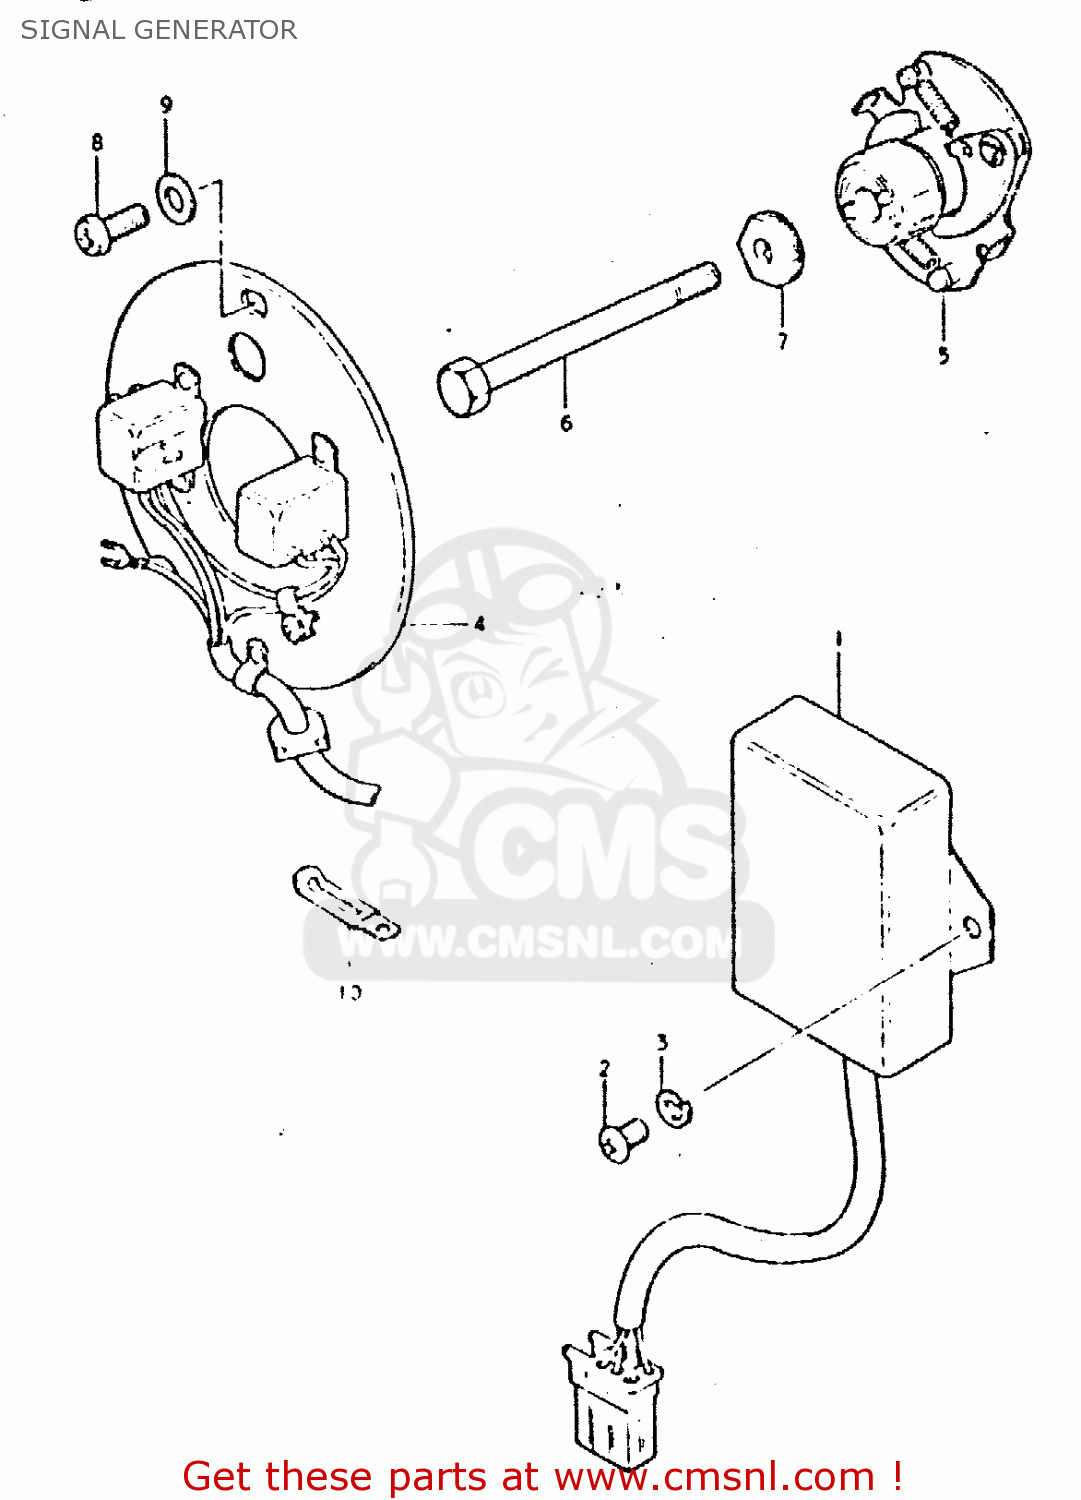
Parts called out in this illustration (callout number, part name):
1	CDI UNIT KOKUSAN
2	SCREW
3	LOCK WASHER
4	SIGNAL GENERATOR ASSEMBLY
5	GOVERNOR ASSEMBLY
6	BOLT 6X60
7	WASHER,CONTACT BREAKER
8	SCREW(5X12)
9	WASHER
10	CLAMP L:35
